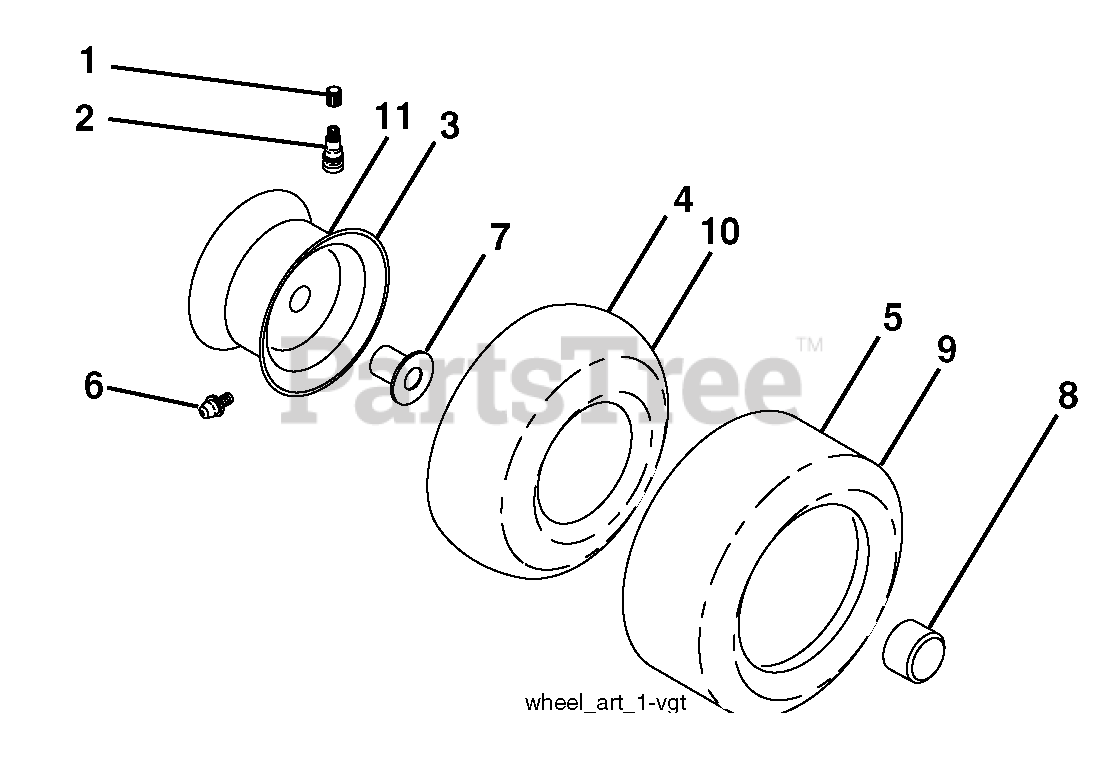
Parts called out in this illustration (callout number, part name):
1	Cap, Valve, Tire
2	Stem, Valve
3	Rim Assembly, Front
4	Tube, Front
5	Tire, Front
6	Fitting, Grease
7	Bearing, Flange
8	Cap, Axle
9	Tire, Rear
10	Tube, Rear
11	Rim Assembly, Rear
11	Sealant, Tire (10 oz. Tube)
